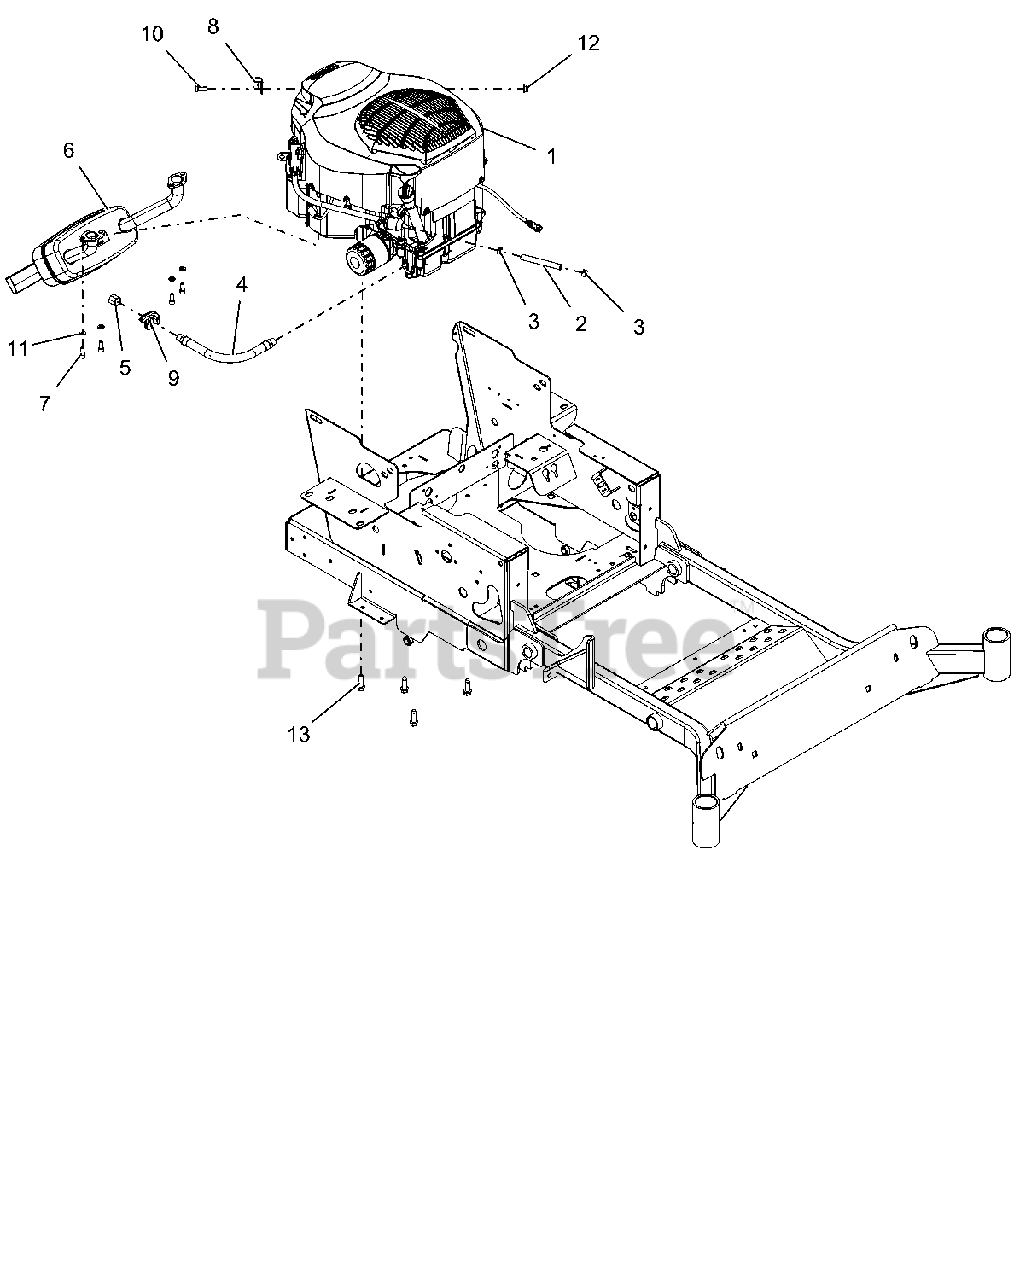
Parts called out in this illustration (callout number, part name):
1	ENGINE, KOHLER TWIN - 25HP PRO
2	HOSE, .25 LOW-PERM BULK GAS
3	CLAMP, FUEL LINE
4	HOSE,HYD .38-11-0K M6NO-M6N0
5	PIPE CAP 3/8 NPT FEMALE
6	MUFFLER, KOHLER
7	SCR-CAP .31-18X.75 S/HD
8	CLAMP, CUSHIONED STEEL .75
9	PROTECTOR, OIL DRAIN HOSE
10	BOLT-HEX.31-18X.875 YWZC GR5
11	@WSHR-LK .31X.078 REG YWZC
12	@NUT-LK-NYL-FLG .31-18 YWZC
13	@SCR-TAP .38-16X1.25 HWH TR YZ
